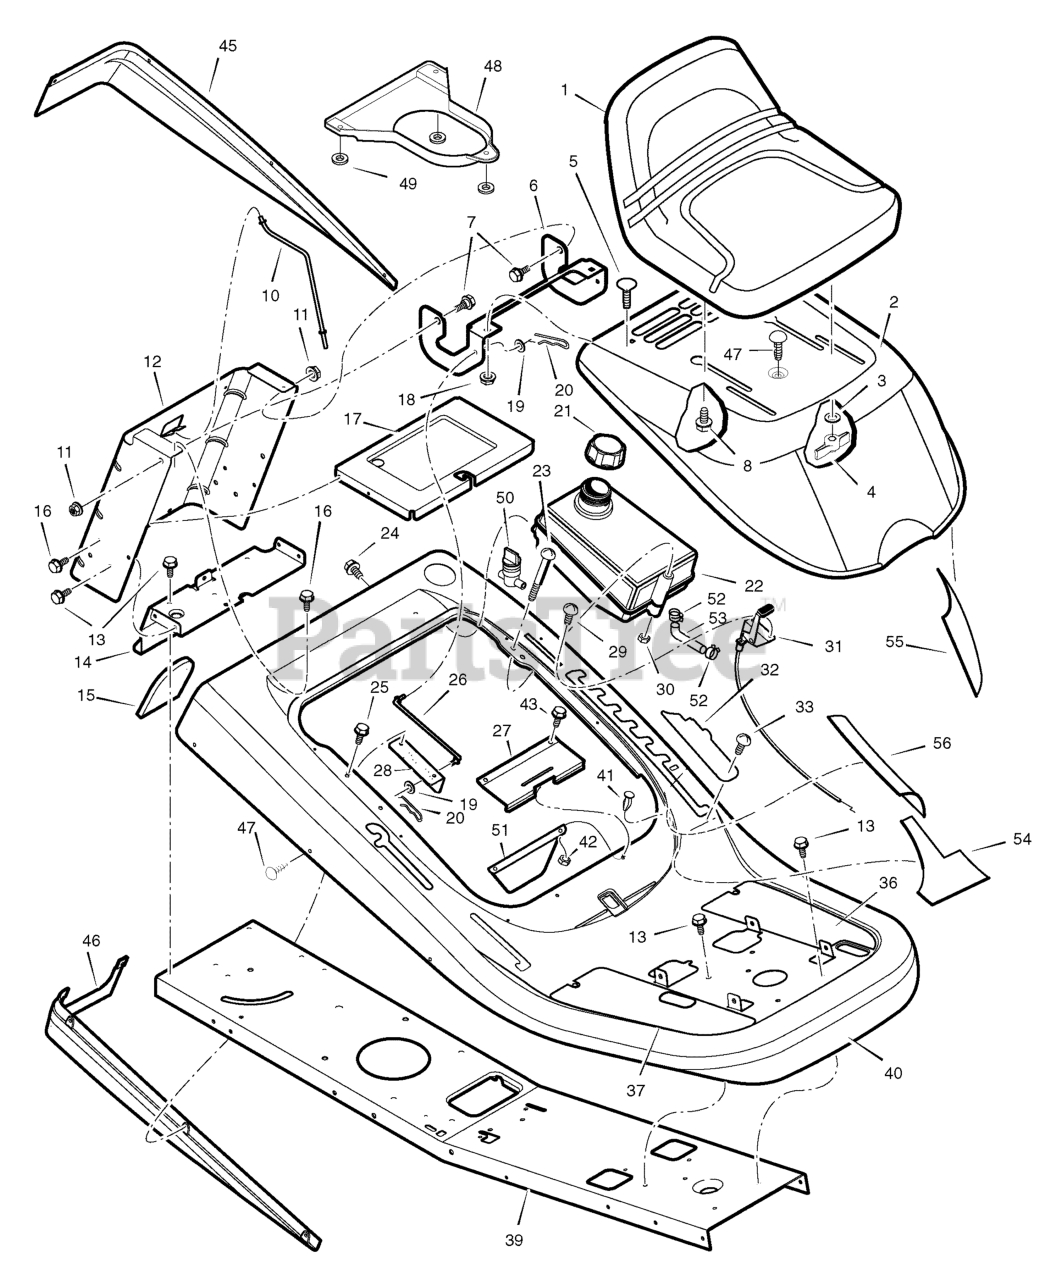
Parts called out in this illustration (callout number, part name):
4	BOLT, Wing
5	BOLT, Carriage
6	BRACKET, Hinge
7	BOLT, Shoulder
8	BOLT, Shoulder
10	ROD, Battery
11	NUT, Flange
12	PLATE, Rear
14	PLATE, Hitch
17	TRAY, Battery
18	NUT, Flange
20	PIN, Cotter
21	CAP, Fuel Tank
22	TANK, Fuel
23	SCREW
26	ROD, Hood Prop
27	SPRING, Seat Deck
28	BRACKET, Prop Rod
30	NUT, NY-Lock
31	CONTROL, Throttle
32	COVER, Detent (Black)
33	BOLT, Shoulder
36	FOOTMAT, Left (Black)
37	FOOTMAT, Right (Black)
42	NUT
44	KIT, Foil Heat Shield
45	TRIM, Left
46	TRIM, Right
47	FASTENER, Panel
49	NUT, Hex 5/16-18
50	VALVE, Fuel Shutoff
51	SHIELD, Heat
52	HOSE, Clamp
53	FUEL, Hose
54	HEAT SHIELD, Hood
55	REFLECTOR TAPE, Heat Shield Hood
56	REFLECTOR TAPE, Heat Shield Upper
